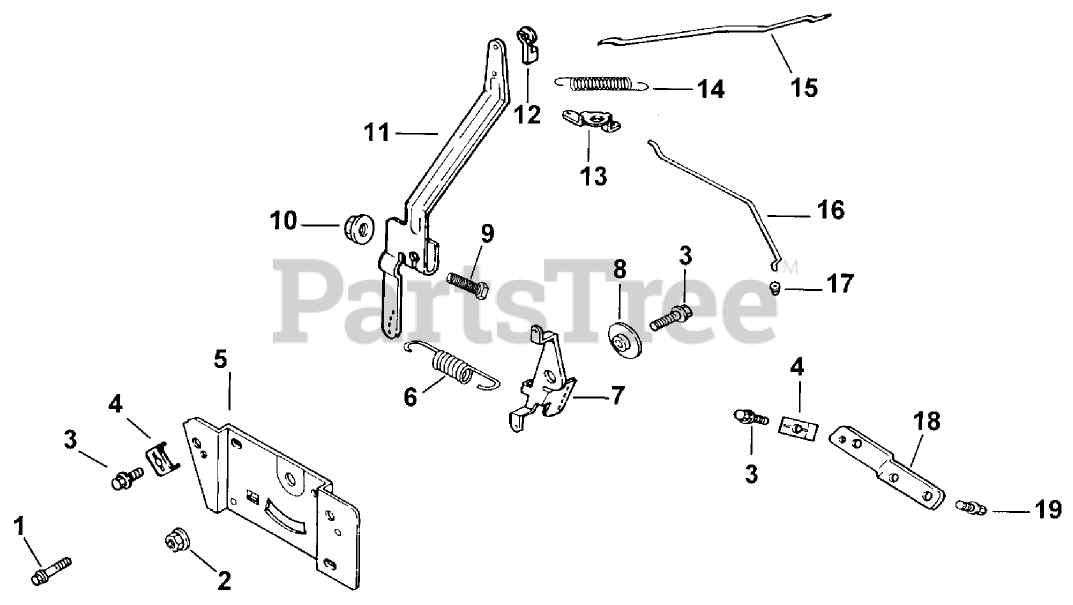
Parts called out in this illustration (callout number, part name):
1	Screw Socket
2	Nut, hex. flange M5x0.8
3	Screw M5x0.8x16 (Only On: 72042, 72063, 72062, 72043)
4	Clamp
5	Plate, control
6	Spring, governor
7	Lever, throttle control
8	Spacer, throttle control
9	Screw
10	Nut
11	Lever, governor
12	Bushing-Linkage
13	Lever, choke-upper
14	Spring, linkage
15	Linkage, throttle
16	Linkage, choke-upper
17	Bushing
18	Bracket, choke mount
19	Screw
